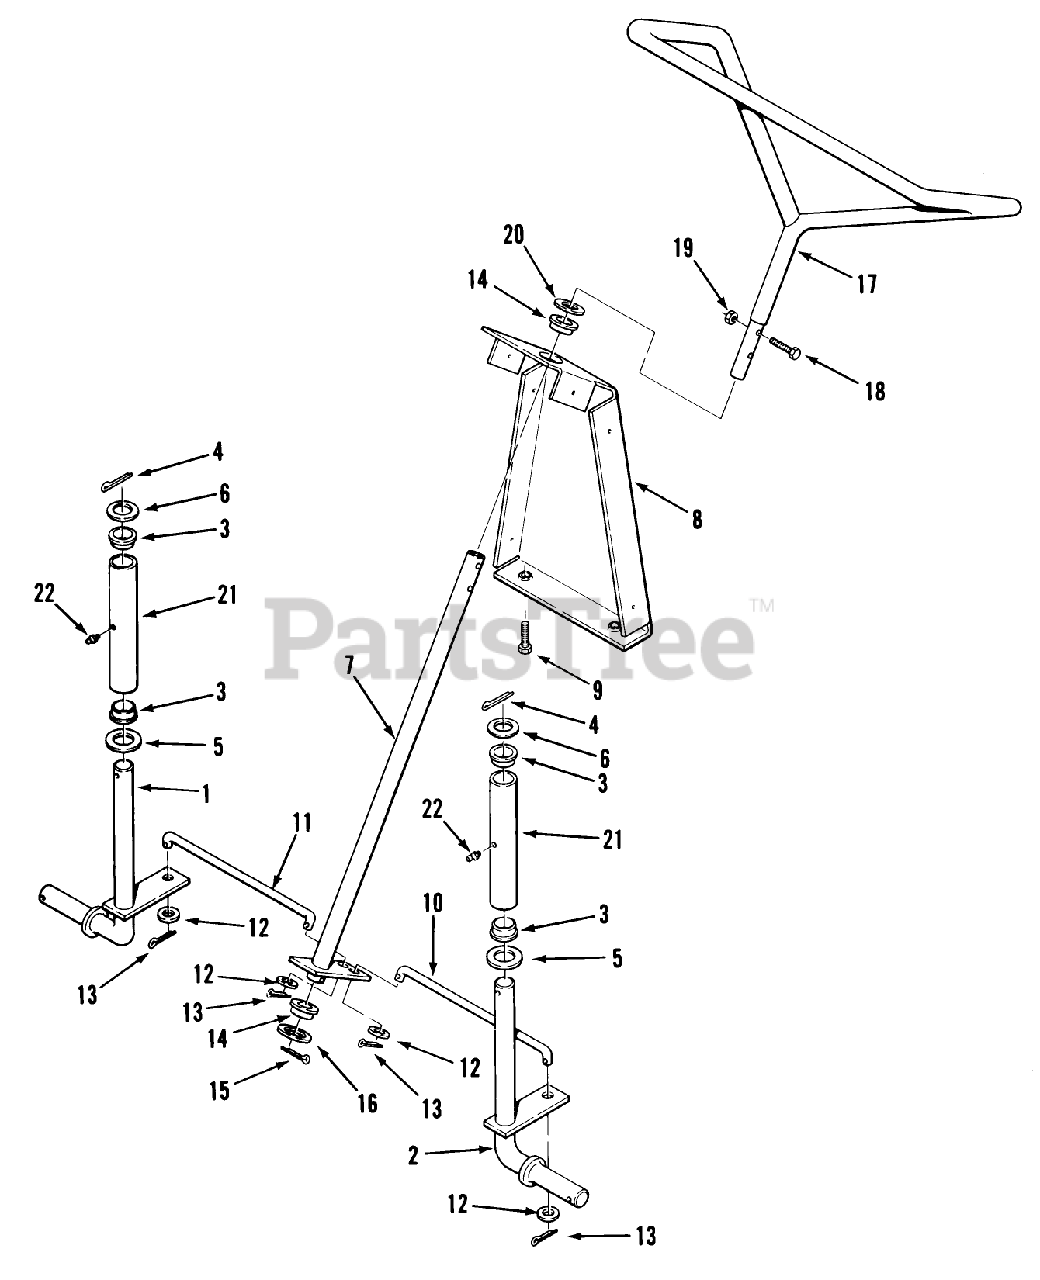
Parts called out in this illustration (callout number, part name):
1	SPINDLE ASSY RH *R
2	SPINDLE ASSY LH *R
3	BUSHING
6	WASHER
9	Screw
12	Washer-3/8
14	BEARING
16	WASHER-FLAT
